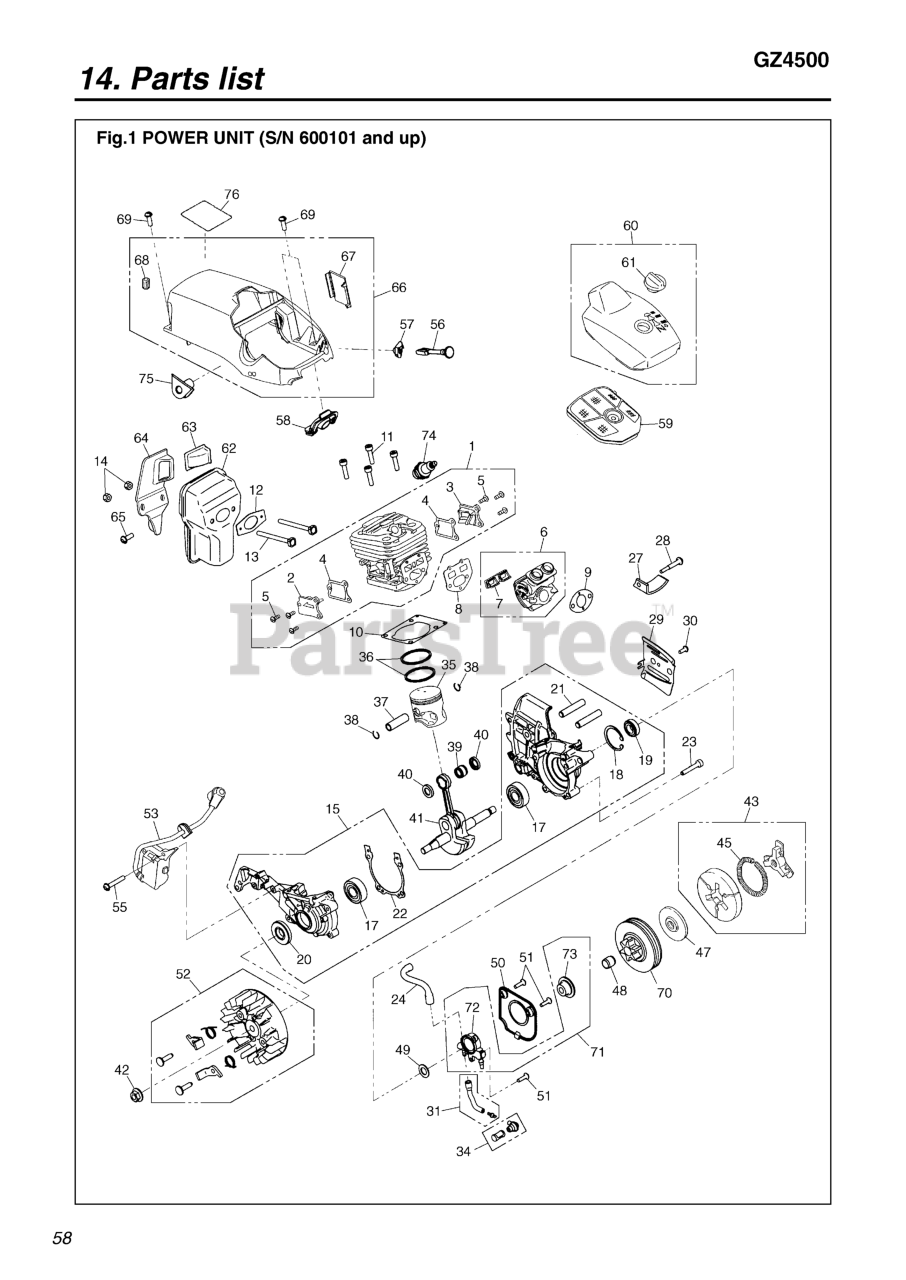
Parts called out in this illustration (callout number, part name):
1	CYLINDER ASSY
2	TR COVER MAG
3	TR COVER PTO
4	GASKET
6	INSULATOR ASSY
7	SEAL
8	GASKET
9	GASKET
10	GASKET
11	BOLT (RPLS 2850-14220)
12	GASKET, MUFFLER
13	BOLT, MUFFLER
14	NUT, MUFFLER (RPLS 3356-15230
15	CASE ASSY
17	BEARING
18	RING, SNAP, M32 x 1.2
19	SEAL, OIL (RPLS 1100-21210)
20	SEAL
21	STUD (RPLS 0205-50825)
22	GASKET
23	BOLT
24	PIPE
27	CATCHER
29	PLATE (A)
31	PIPE IN COMP.
34	FILTER COMPLETE
35	PISTON
36	RING
37	PIN
38	RING, SNAP
39	BEARING
40	WASHER
41	SHAFT COMP
43	CLUTCH ASSEMBLY
45	SPRING
47	PLATE
48	BEARING
49	WASHER
50	COVER, PUMP
51	SCREW
52	ROTOR COMP
53	COIL ASSY
55	SCREW
56	ROD, CHOKE
57	GROMMET, CHOKE
58	GROMMET, THROTTLE
59	CLEANER ASSY
60	COVER COMP
61	KNOB (RPLS 3356-83322)
62	MUFFLER
63	ARRESTER, SPARK
64	STAY
65	SCREW (REPLACES 2616-24320)
66	COVER COMP
68	GROMMET (RPLS-31151)
69	SCREW
70	DRUM 0.325-7
71	OIL PUMP ASSY
74	SPARK PLUG
75	GROMMET
